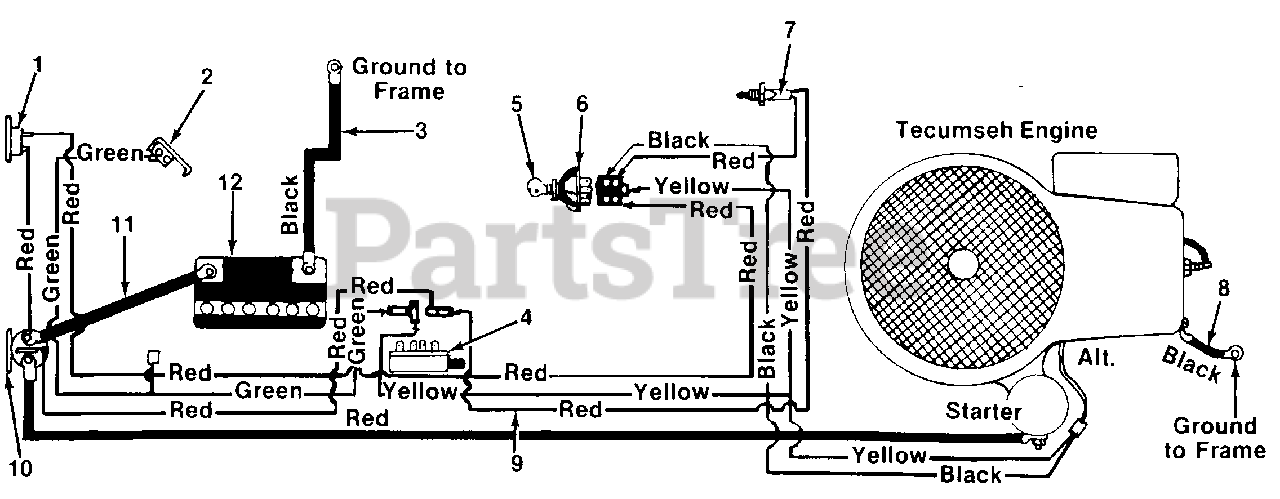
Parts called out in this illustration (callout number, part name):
1	Circuit Breaker
2	Spring Switch
3	Ground Wire 9.0" Lg.
4	Safety Switch
5	Ignition Key
6	Ignition Switch
7	Safety Switch
8	Ground Wire 7.25" Lg. (Black)
9	Wire Harness
10	Solenoid
11	Electric Wire w/Boot
12	1 2V-Battery
